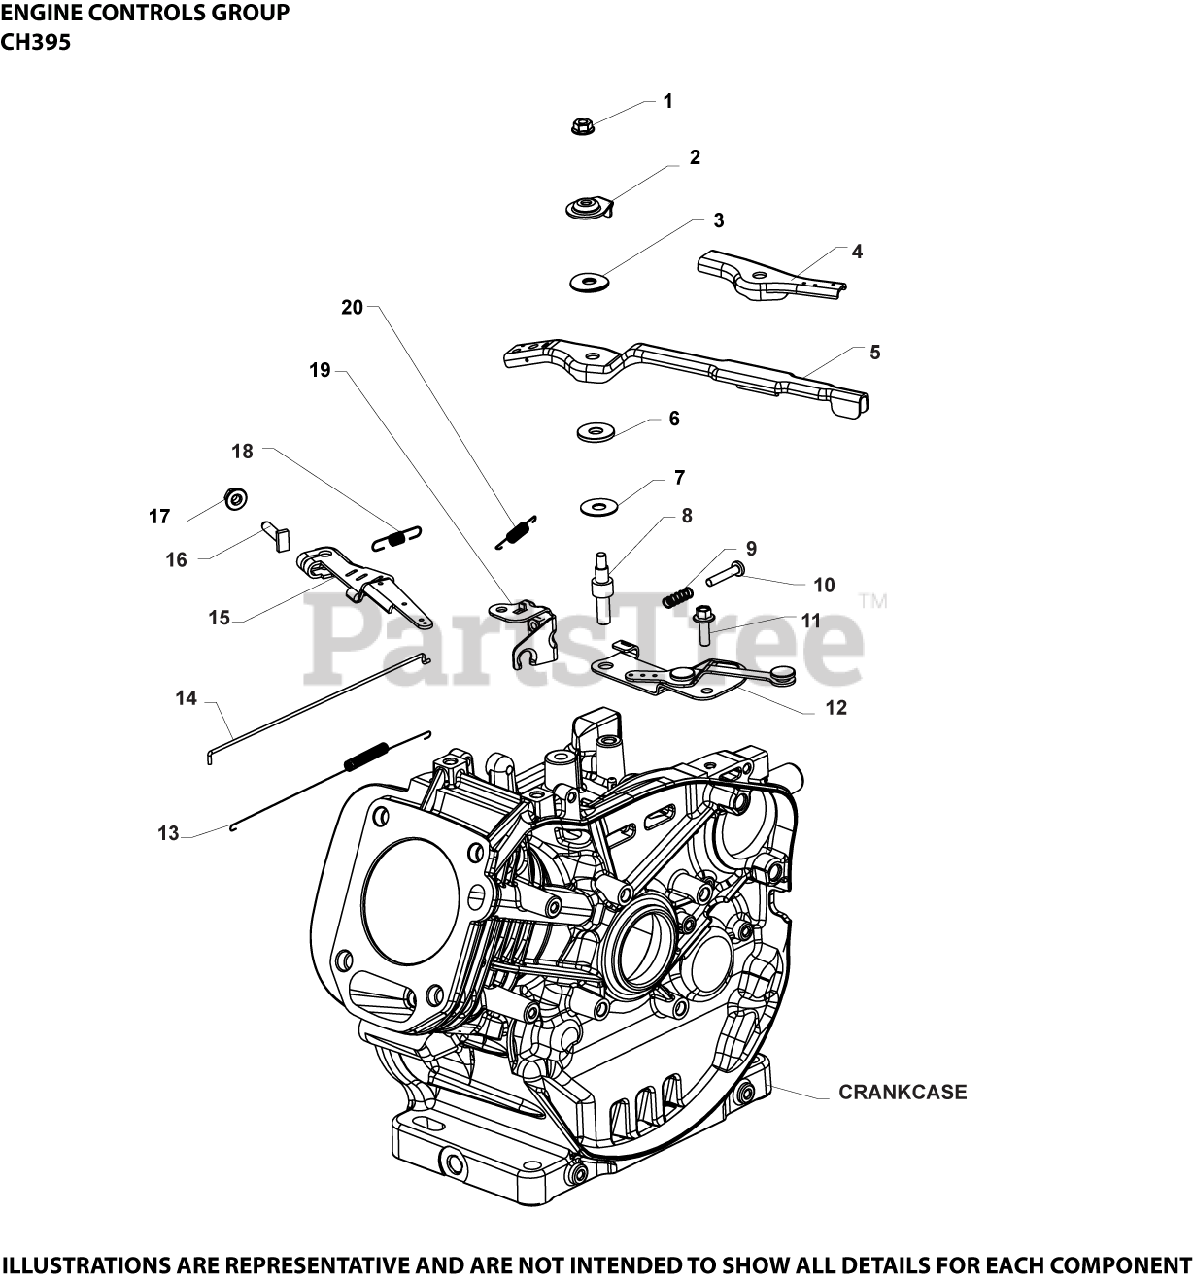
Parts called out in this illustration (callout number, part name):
1	NUT, HEX FLANGE LOCK (M6)
2	WASHER, CONTROL LEVER - USE 17 468 34-S
3	WASHER, SPRING
6	WASHER, NYLON CONTROL LEVER
7	WASHER, FLAT
8	STUD, CONTROL LEVER
9	SPRING, COMPRESSION
10	SCREW, SPEED ADJUSTING
11	SCREW, M6 X18
12	BRACKET, CONTROLS ASSY
13	SPRING, LINKAGE
14	LINKAGE, GOVERNOR
15	KIT, GOVERNOR LEVER USE 17 090 54-S
16	SCREW, RECTANGLE HEAD (M6)
17	NUT, FLG M6X1.0
18	SPRING, GOVERNOR
